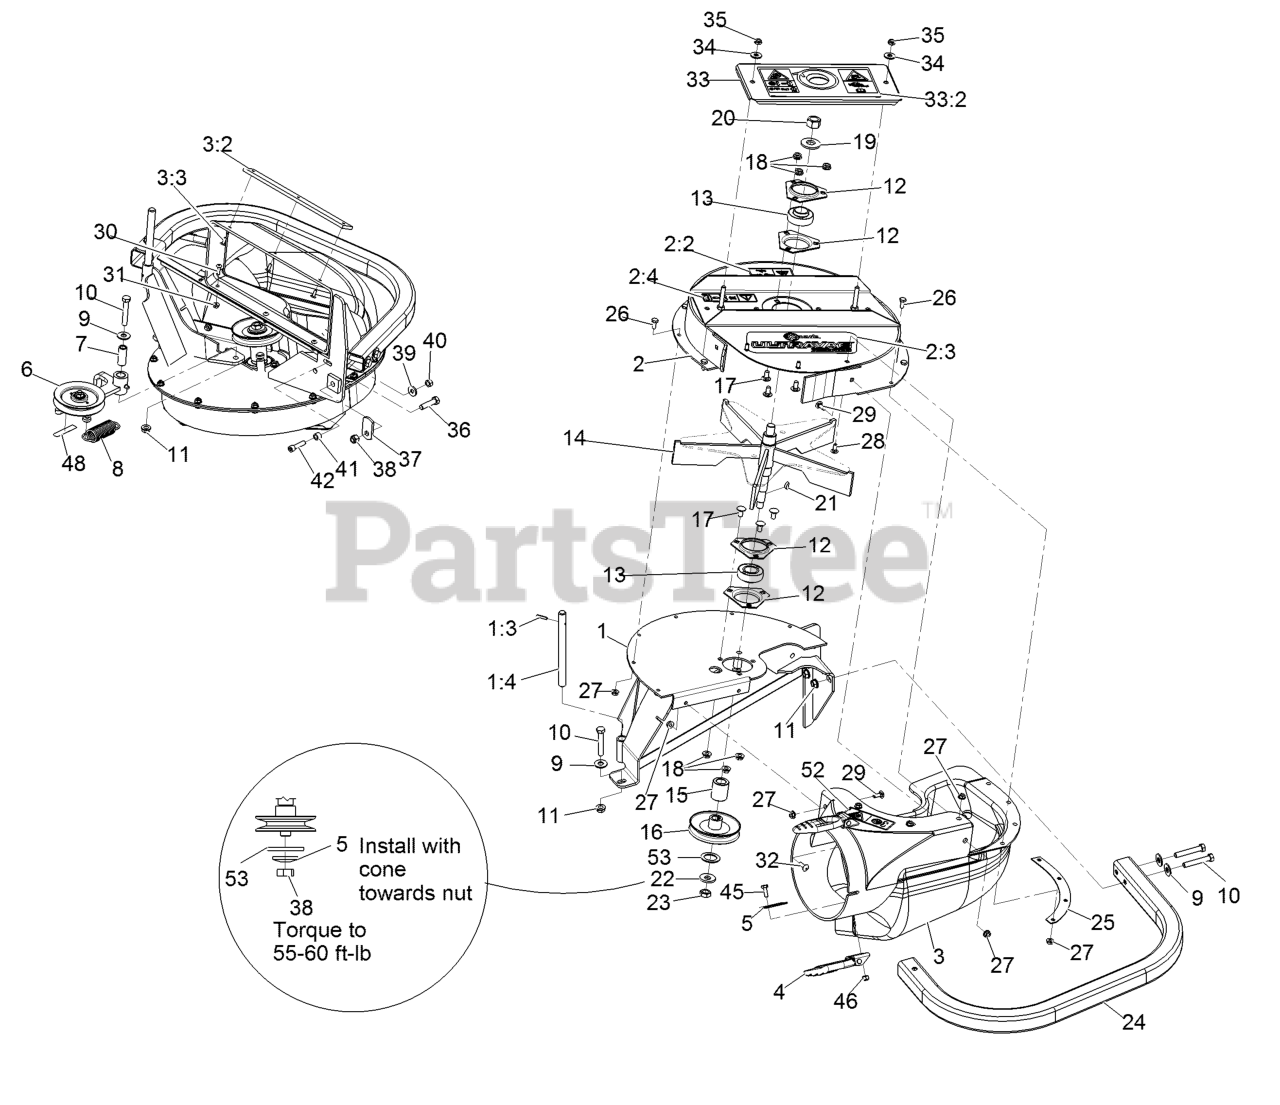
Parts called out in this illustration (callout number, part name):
1	Wld,Frame Lg Blower
1:3	Rollpin 3/16 X 7/8
1:4	Shaft-Catcher, Grass
2	ASM-Upper Housing Large
2:2	Decal-Warning, Traction
2:3	Decal-Ultravac X-Series
2:4	Decal-Missing, Cover
3	Asm, Blower Chute
3:2	Plate, Reinforcement
4	Latch-Rubber
5	Plate-Backing
6	ASM, Idler
7	Bushing
9	Washer-3/8 Std
10	Screw-HH 3/8-16 X 2 1/4
11	Nut-Whizlock 3/8-16
12	Housing-Flange
13	Bearing
14	Impeller
17	Bolt-Carriage 5/16-18 X 5/8
18	Nut-Whizlock 5/16-18
19	Washer-Spring Disc 5/8
20	Nut-Hex 5/8-18
21	Key-Woodruff 3/16 X 5/8
22	Washer-Spring Disc 1/2
23	Nut-Jam 1/2-20
25	Plate-Backing, Blower
26	Screw-HH 1/4-20 X 5/8
27	Nut-Whizlock 1/4-20
28	Bolt-Carriage 1/4-20 X 5/8
29	Bolt-Carriage 1/4-20 X 3/4
30	Screw-Truss Head #10-24 X 3/4
31	Nut-Whizlock #10-24
32	Screw-PPH 1/4-20 X 3/4
33	Cover, Bearing W/Decal
33	Cover, Bearing With Decal
33:2	Decal, Warning
34	Washer-5/16 Std
35	Nut-Nyloc 5/16-18 Thin
36	Screw-HH 3/8-16 X 1 1/2
37	Latch-Catcher, Grass
38	Nut-Nyloc 3/8-16
39	Washer-Spring Disc 5/16
40	Nut-Hex 5/16-18
41	Bushing
42	Screw-Sh 5/16-18 X 1 1/4
45	Screw-HH 1/4-20 X 3/4
46	Nut-Nyloc 1/4-20
48	Decal-Warning
52	Decal-Warning
